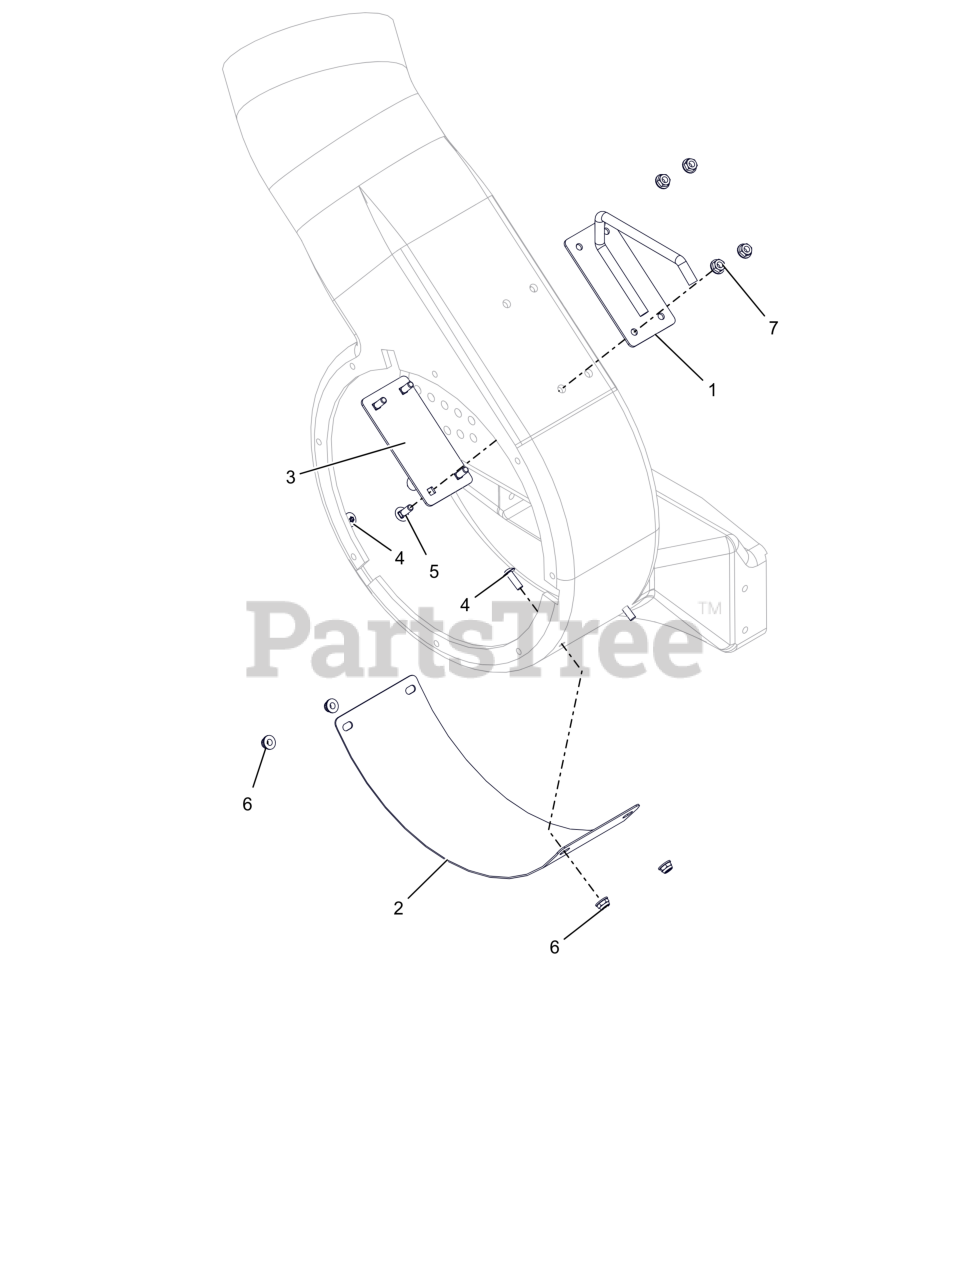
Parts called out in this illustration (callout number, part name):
1	WLDMT, HOUSING HANDLE (BLACK)
2	PLATE, SKID
3	PLATE, HANDLE BACKER (BLACK)
4	SCR-MCH .25-20X.75 TXTR YWZC
5	BLT, RHSN .25-20X.750 G5 ZCC
6	NUT,NYL-FLG .25-20 GF ZCC
7	NUT-LK-CTR-FLG .25-20 ZC120
